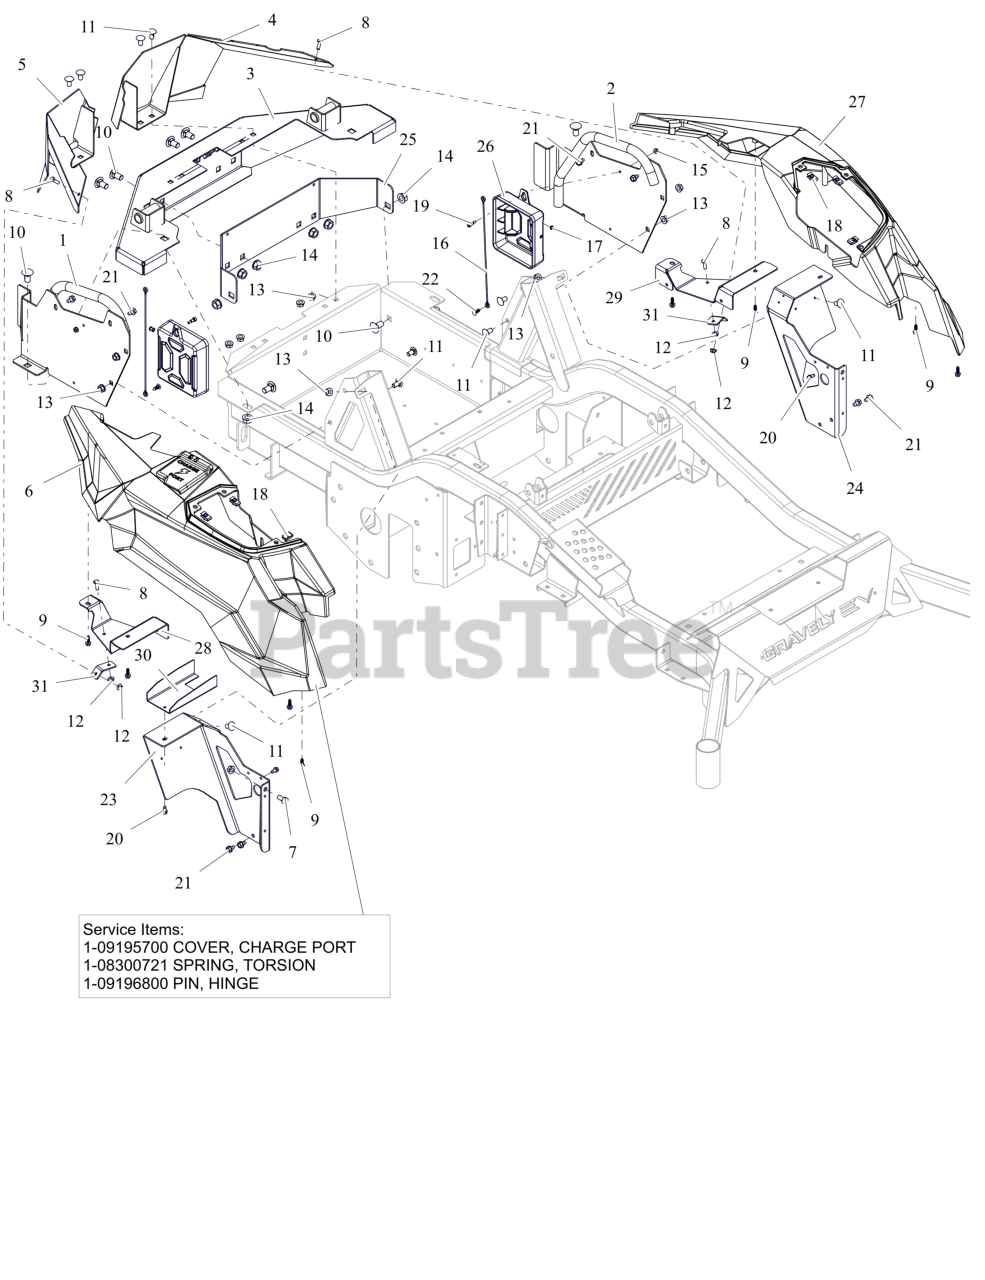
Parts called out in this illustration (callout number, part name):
1	WLDMT, REAR FENDER MOUNT-RH (RED)
2	WLDMT, REAR FENDER MOUNT-LH (RED)
3	WLDMT, BUMPER PT EV (RED)
4	WLDMT, REAR WRAP-LH (BLACK)
5	WLDMT, REAR WRAP-RH (BLACK)
6	ASM, FENDER RH PRO-TURN EV
6	COVER, CHARGE PORT
6	SPRING, TORSION
6	PIN, HINGE
7	BLT,HEX .38-16X.75 G5 ZCC
8	BLT, HEX .25-20X.75 G5 ZCC
9	SCR, PLASTITE-HWH 0.25 X 0.75 ZC120
10	BLT, RHSN .50-13X1.00 G5 ZCC
11	BTL,RHSSN .375-16 X 0.75 G5 FPB
12	NUT-LK-CTR-FLG .25-20 ZC120
13	NUT-LK-CTR-FLG .375-16 GF ZCC
14	NUT-LK-CTR-FLG .500-13 GG ZCC
15	NUT, FLG-TOP LK #10-24 GRF ZCC
16	CABLE, 12.0 LANYARD, NYLON
17	POST, & SCREW, PUSH LOCK .25 X .25
18	NUT-RTNR .25-20X.56
19	BLT-SHLDR .25X.375
20	SCR-TAP .25-20X.50 HWH ZCC
21	SCR,TAP .312-18X.50 HWH TR ZCC
22	RIVET, .25 NYLON PANEL
23	MOUNT, FRONT FENDER-RH
24	MOUNT, FRONT FENDER-LH
25	SUPPORT, BUMPER (BLACK)
26	COVER, BATTERY BUSBAR TERMINAL
27	FENDER, LH PRO-TURN EV
28	SHIELD, FENDER MOUNT -RH (BLACK)
29	SHIELD, FENDER MOUNT-LH (BLACK)
30	SHIELD, DEBRIS -CHARGE PORT (BLACK)
31	STRAP, SUPPORT - REAR WRAP (BLACK)
